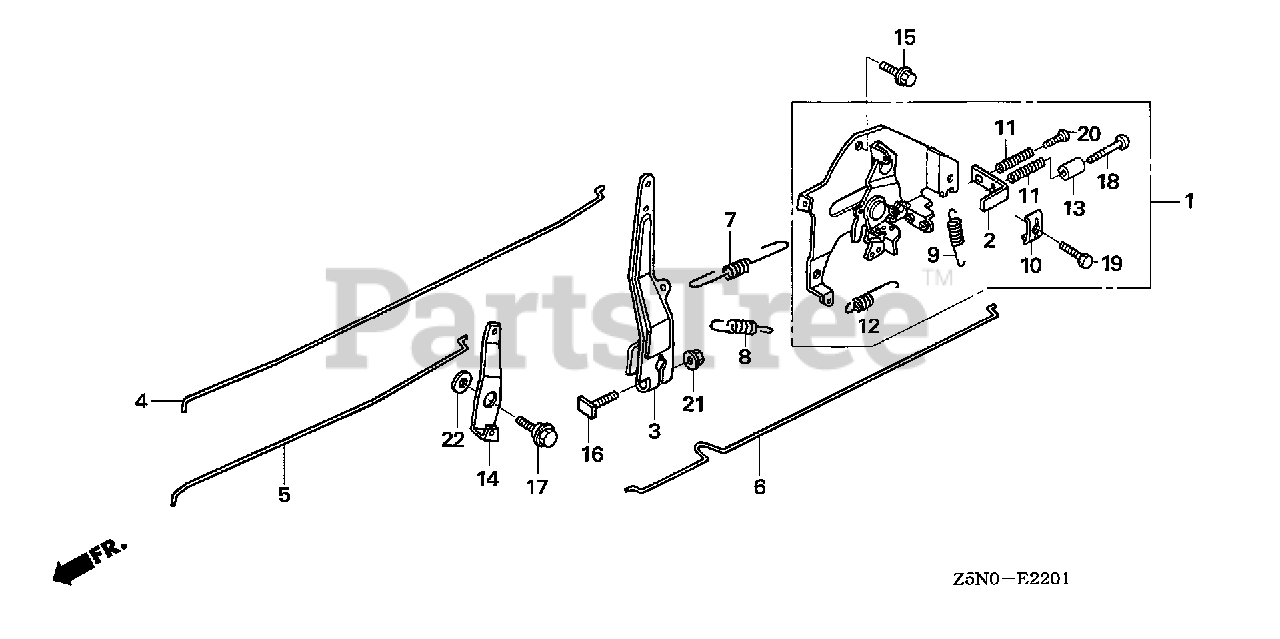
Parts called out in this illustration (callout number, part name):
1	CONTROL ASSY.
2	PLATE, SCREW ADJUST GUARD
3	ARM, GOVERNOR
4	ROD, GOVERNOR
5	ROD, CHOKE
6	ROD, JOINT
7	SPRING, GOVERNOR
9	SPRING, LEVER
10	HOLDER, CABLE
11	SPRING, CONTROL ADJUSTING
12	SPRING, CABLE RETURN
13	COLLAR, STOPPER
14	LEVER, CHOKE JOINT
15	BOLT, FLANGE (6X12) (CT200)
16	BOLT, GOVERNOR ARM
17	BOLT, FLANGE (6MM)
18	SCREW, RECESSED (5X35)
19	BOLT, RECESSED (5X16)
20	BOLT, RECESSED (5X22)
21	NUT, FLANGE (6MM)
22	WASHER, PLAIN (6MM)
